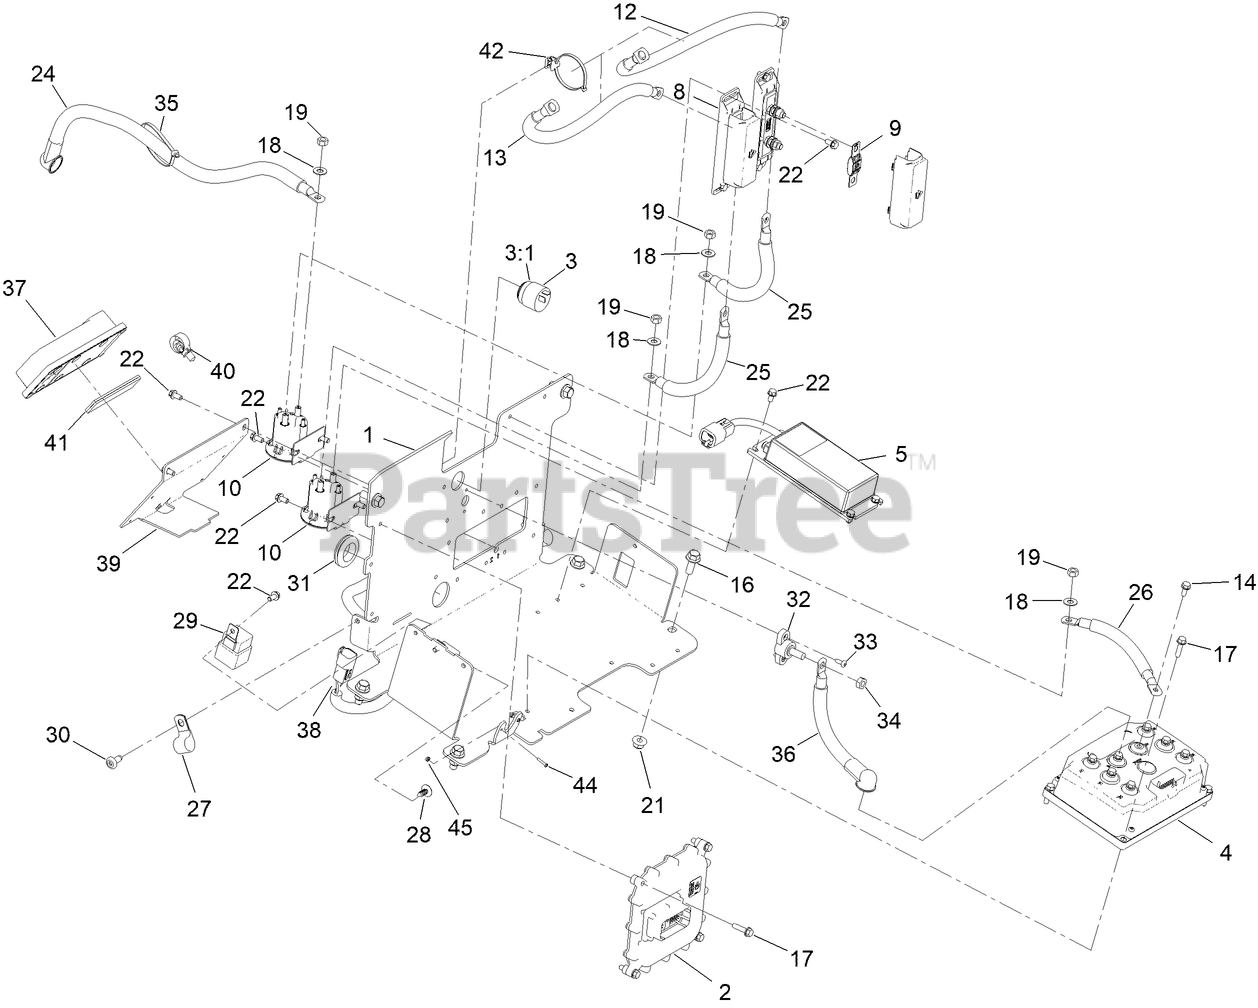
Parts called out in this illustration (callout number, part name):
1	PLATE-MNT, ELECTRICAL
2	CONTROLLER
3	AUDIO ALARM ASM
3:1	NUT-PLASTIC, KNURLED
4	INV/CTRLR-48V,DUAL 94Arms
5	CONVERTER DC-DC
8	HOLDER-FUSE
9	FUSE-200A
10	CONTACTOR-DC, 12V
12	CABLE-BATTERY, RD ASM
13	CABLE-BATTERY, RD ASM
14	SCREW-SEMS
16	SCREW-HHF
17	SCREW-HWHTF
18	WASHER
19	NUT-HEX
21	NUT-HF, NI
22	SCREW-HWH
24	CABLE-BATTERY, RD ASM
25	CABLE-BATTERY, RD ASM
26	CABLE-BATTERY, RD ASM
27	CLAMP-R
28	PLUG-PLASTIC
29	RELAY
31	GROMMET
32	BLOCK-JUNCTION
33	SCREW-FORMING, THREAD
34	NUT-HEX
35	TIE-CABLE
36	CABLE-BATTERY, BK ASM
37	CONTROLLER, CALAMP-NA
38	HARNESS-WIRE
39	PLATE-MOUNT, CALAMP
40	CLIP-TIE
41	STRIP-FASTENER, ADHESIVE
42	CLIP-HARNESS. EDGE, W/TIE-WRAP
44	SCREW-PPH
45	NUT-HEX, NYL INS
